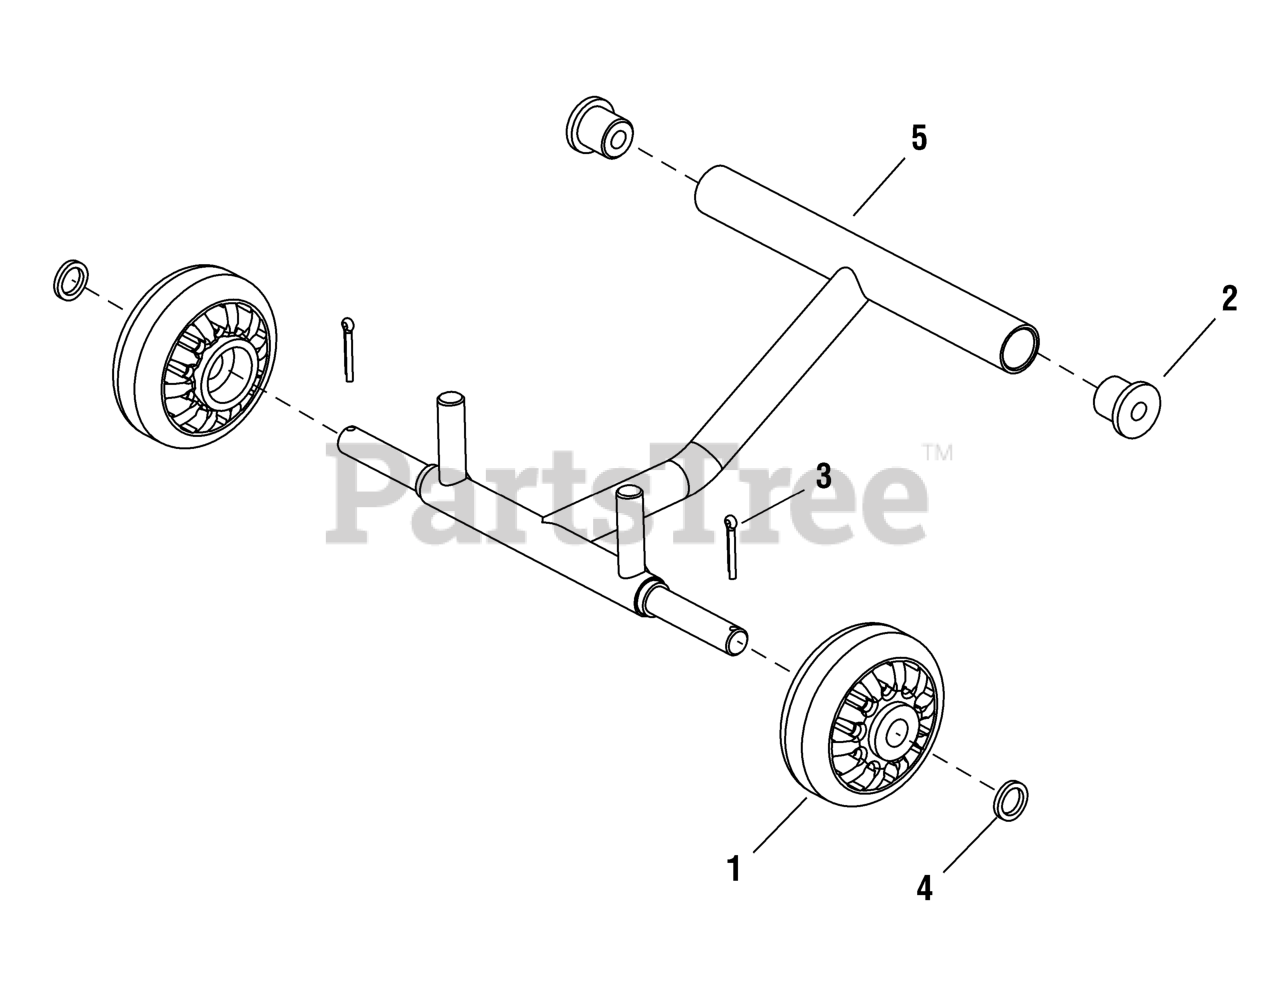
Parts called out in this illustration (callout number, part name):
2	BUSHING, Nylon
3	SPLIT PIN
4	WASHER
5	WHEEL FRAME
